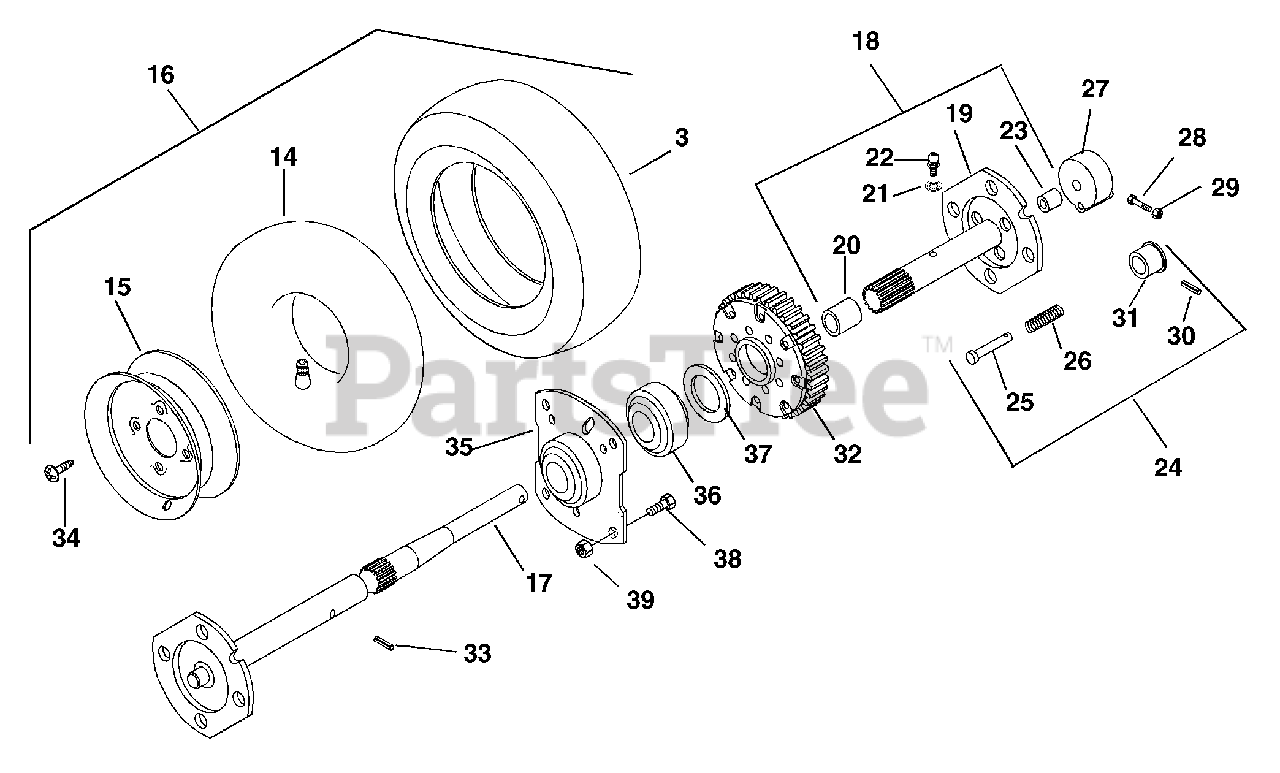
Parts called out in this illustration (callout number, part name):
3	TIRE 4.80-8 NHS
3	TIRE 16X6.50-8 SNO-HOG TREAD
14	TUBE
15	WHL
16	T/WHL ASSY 4.80-8
16	T/WHL ASSY 16X6.50-8 SNO-HOG
17	R H AXLE
18	L.H. AXLE ASSEMBLY
18	L.H.AXLE ASSEMBLY
19	L H AXLE
20	BSHG-SLV .750X.814X .750 BRZ
21	WSHR-LK .250X.047 LT YWZC
22	FTG-LUBE .25-28X.256 YWZC
23	BSHG-SLV .562X.625X.625 BRZ
24	LOCKOUT HUB ASSEMBLY
25	PIN
26	SG-COMP .028X.34X1.062 WLD75
27	LOCKOUT HUB
28	BLT-HEX .25-20X2.0 PL GR8 YWZC
29	NUT-JAM-NYL .250-20 W/INSERTYZ
30	PIN-ROLL .093X1.00
31	KNOB
32	DIFFERENTIAL ASSEMBLY
33	PIN-ROLL .188X1.50
34	SCR-TAP .500-20X.62 HH YWZC
35	BEARING RETAINER
36	BRG-BALL 1.13X2.19X.63
37	WSHR-FL-STL 1.140X1.718X.134YZ
38	BLT-SERNK SL .25-20X.50 YWZC
39	@NUT-SPNLK-FLG .25-20 YWZC
